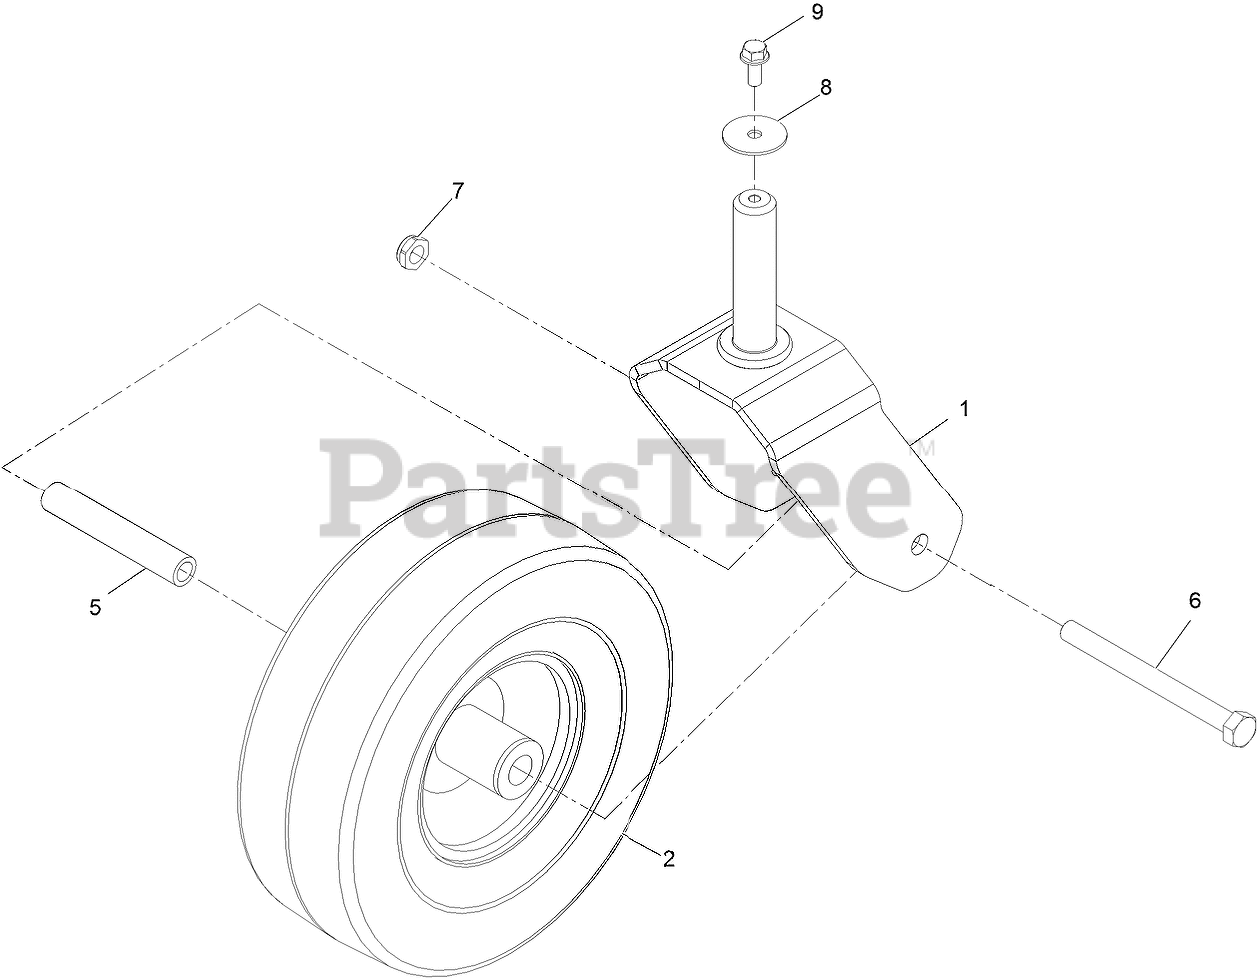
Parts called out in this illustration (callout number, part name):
2	TIRE AND WHEEL ASM (C S T)
5	BUSHING-SPANNER
6	SCREW-HH
7	NUT-HEX
8	WASHER-FLAT
9	SCREW-HHF
